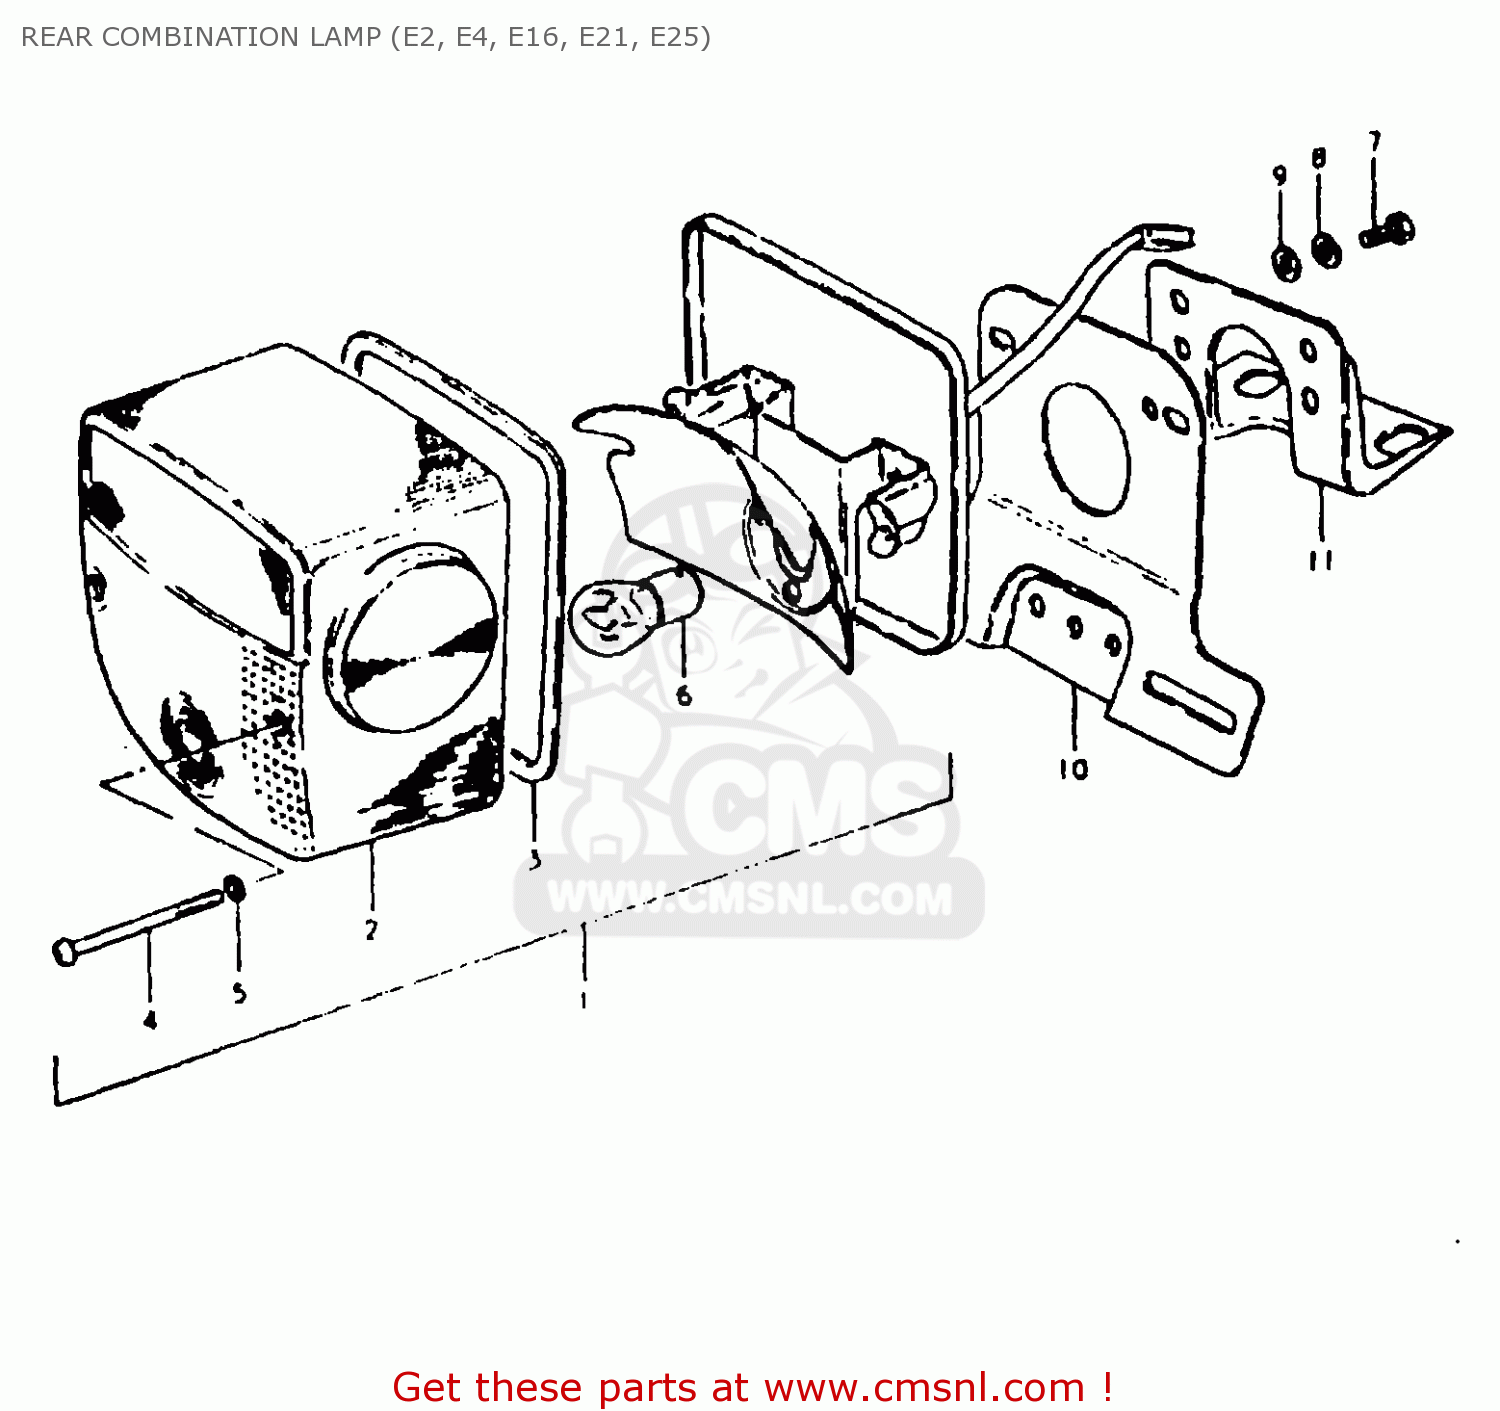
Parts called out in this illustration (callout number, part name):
1	LAMP ASSY, REAR COMBINATION
2	LENS
3	GASKET (NAS)
4	SCREW (4X55)
5	GASKET (NAS)
6	BULB 12V21/5W
7	BOLT
8	LOCK WASHER
9	WASHER
10	PLATE, LICENCE
11	BRACKET,LICENSE PLATE
